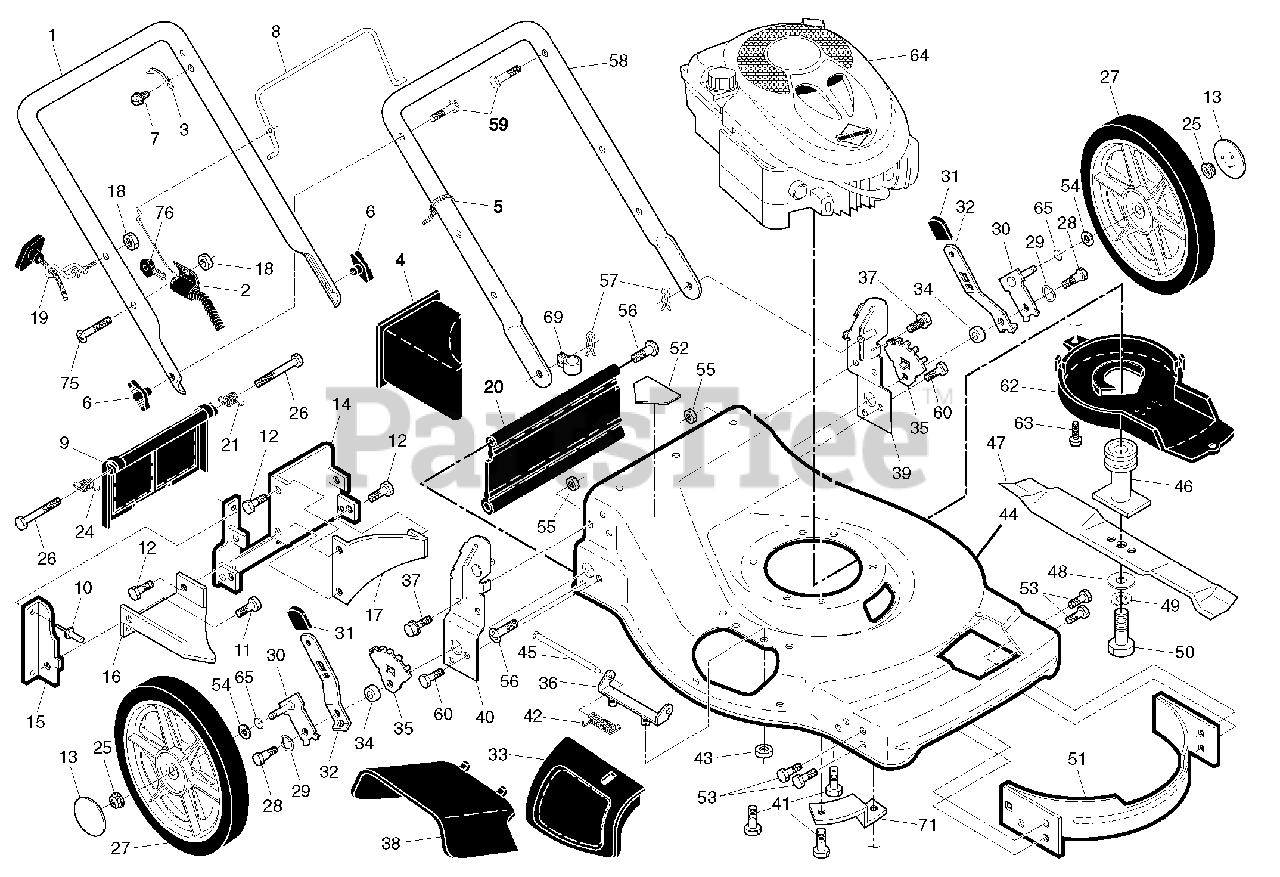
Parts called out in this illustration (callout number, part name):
1	Upper Handle
2	Key Start Switch
3	Bracket, Upstop
4	Mulcher Plug
5	Wire Tie
6	Handle Knob
7	Screw
8	Control Bar
9	Rear Door Assembly
10	Pop Rivet
11	Screw, Self-Tapping #10-24 x 5/8
12	Screw, Hex Hex Head, Sems 1/4-20 x 1/2
13	Hubcap
14	Back Plate
15	Side Baffle
16	Discharge Baffle
17	Rear Baffle
18	Keps Locknut 1/4-20
19	Rope Guide
20	Rear Skirt
21	Spring, Rear Door, LH
24	Spring, Rear Door, RH
25	Nut, Hex, Flanged
26	Bolt, Rear Door
27	Wheel & Tire Assembly, Rear
28	Bolt, Shoulder 3/8-16 x 1
29	Washer, Curved, Cylindrical
30	Axle Arm Assembly
31	Selector Knob
32	Selector Spring
33	Mulcher Door
34	Spacer
35	Wheel Adjusting Bracket
36	Hinge Bracket Assembly
37	Screw, Sems, Thread Cutting 5/16-18 x 3/4
38	Discharge Deflector
39	Handle Bracket Assembly, LH
40	Handle Bracket Assembly, RH
41	Screw, Hex Head, Threaded, Rolled 3/8-16 x 1-1/8
42	Spring, Torsion
43	Nut, Hex, Nylock
44	Kit, Mower Housing
45	Rod, Hinge
46	Blade Adapter / Pulley
47	Blade, 22"
48	Washer, Hardened
49	Washer, Helical
50	Screw, Machine, Hex Head 3/8-24 x 1-3/8 Grade 8
51	Kit, Front Baffle
52	Danger Decal
53	Screw, Serrated, TT 1/4-20
54	Washer, Flat
55	Nut, Hex 3/8-16
56	Hinge Screw 1/4-20 x 1-1/4
57	Hairpin Cotter
58	Lower Handle
59	Handle Bolt
60	Bolt, Hex Head 3/8-16 x 3/4
62	Debris Shield
63	Screw, Debris Shield
65	O-Ring
69	Clip, Cable
71	Mounting Bracket, Debris Shield
75	Screw
76	Key
76	Operator’s Manual, English
76	Operator's Manual, French
76	Repair Parts Manual
